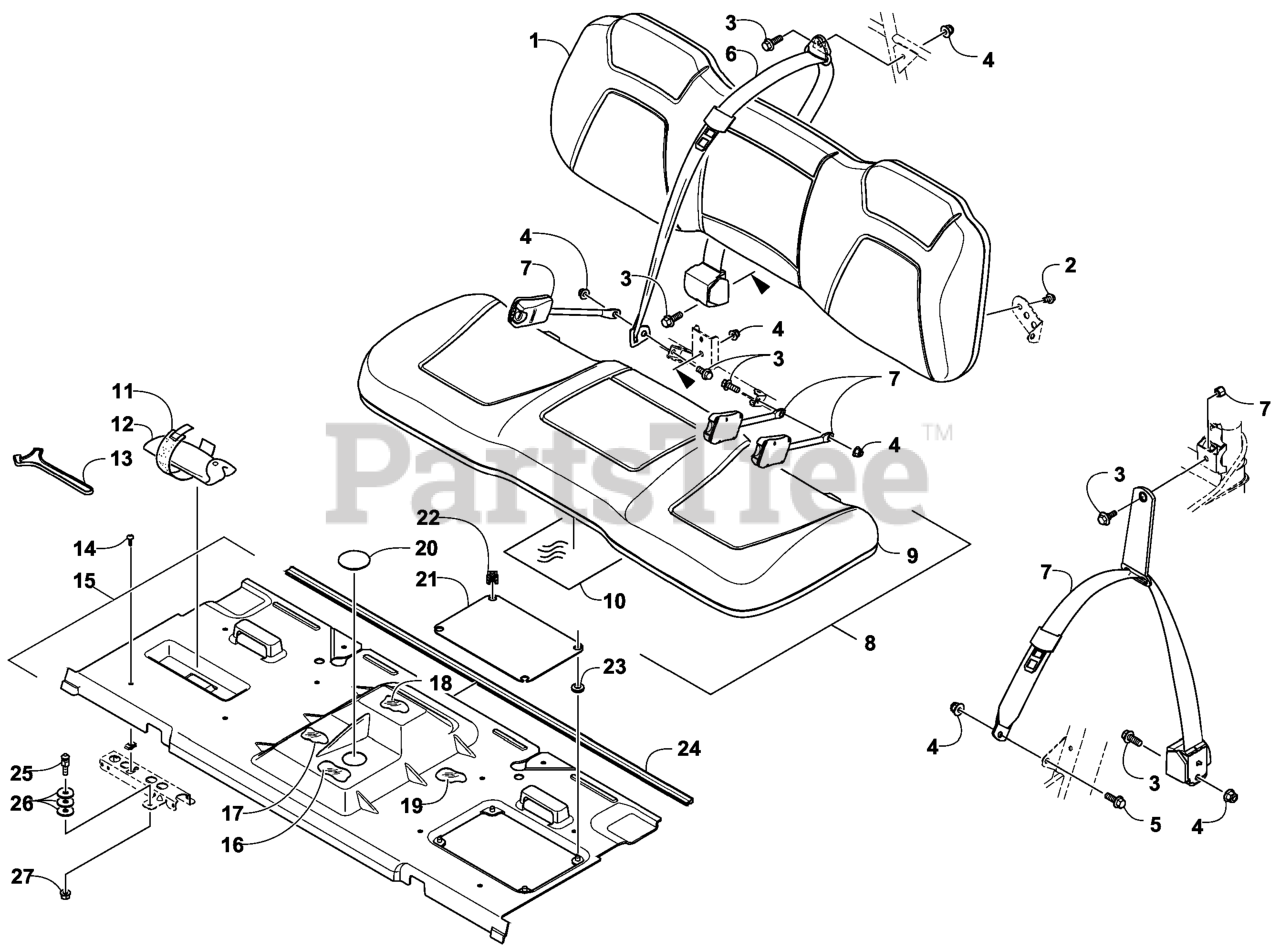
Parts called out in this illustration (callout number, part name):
2	SCREW-HFH
3	SCREW-HFH
4	NUT-HHF, LOCK, (NI)
5	BRACKET-SWITCH, BLADE
6	BELT-SEAT, 3PT
7	BELT-SEAT, 3PT
8	SEAT-BENCH, BOTTOM W/FOIL
9	Seat, Bench
10	FOIL-PROTECTIVE, SEAT
11	Retainer, Toolkit
12	KIT-TOOL
13	WRENCH-SPANNER
15	SEATBASE-CHASSIS
16	SHIELD-SEATBASE (A)
17	SHIELD-SEATBASE (D)
18	SHIELD-SEATBASE (B)
19	SHIELD-SEATBASE (C)
21	COVER-BATTERY BOX, SEATBA
22	CLIP-U NUT
23	GROMMET
24	SEAL-CARGO BOX
25	STUD-LATCH, SEAT
26	WASHER-FLAT
27	NUT-HHF
